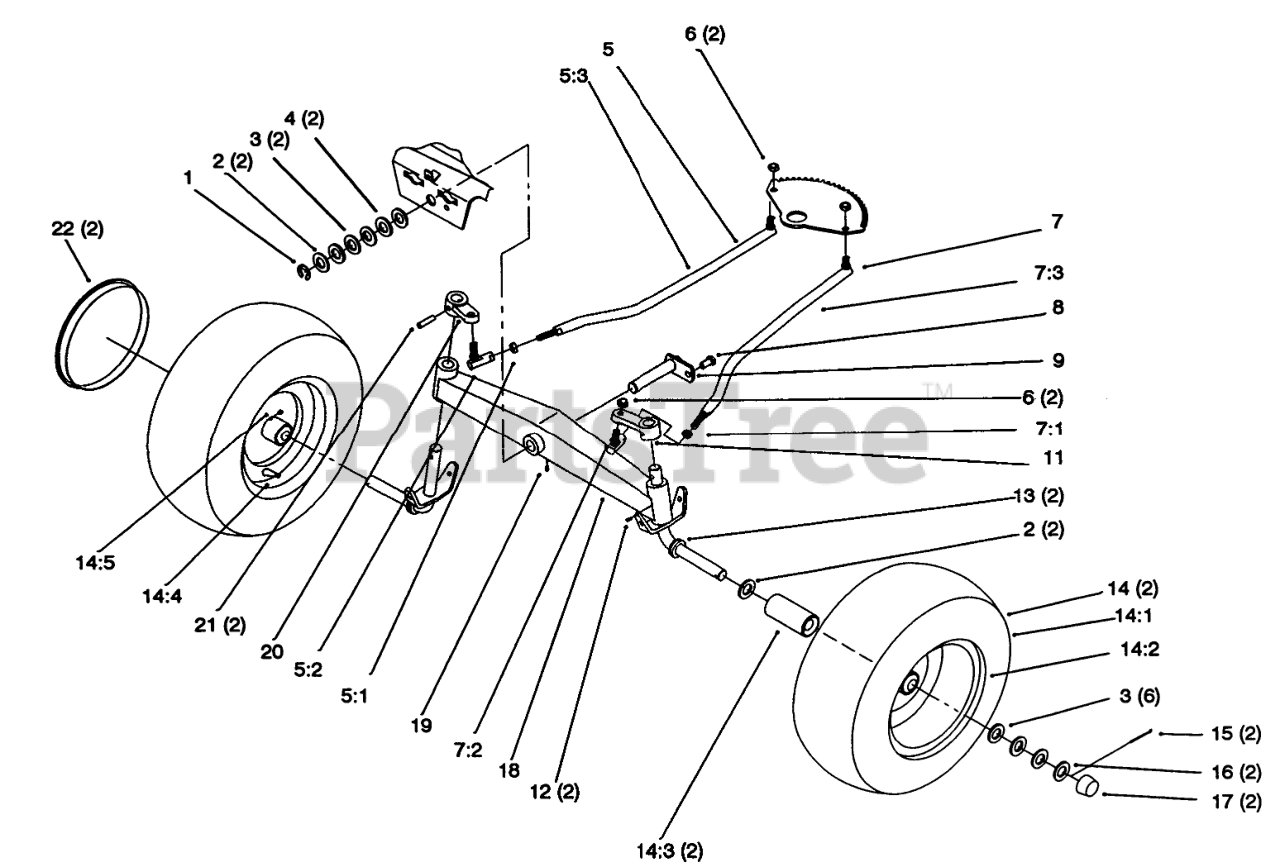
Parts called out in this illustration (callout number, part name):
1	E-RING
2	WASHER-SHIM
3	WASHER
4	Washer
5	LINKAGE-STEERING, RH
5:1	Nut-HJ
5:2	BALL-JOINT
5:3	Ball Link ASM
7	LINKAGE-STEERING, LH
7:1	Nut-HJ
7:2	BALL-JOINT
7:3	Ball Link ASM
8	SCREW-HWH, TAPTITE
9	PIN-AXLE
11	Arm-Front Spindle
12	FITTING-GREASE
13	SPINDLE
14	Wheel AND Tire ASM
14:1	Tire (16 x 6.5-8) 2-Ply -2 Wheel Axel
14:2	Wheel
14:3	BEARING-WHEEL
14:4	VALVE
15	PIN-COTTER
16	WASHER-PLAIN
17	CAP-HUB
18	AXLE-FRONT
19	FITTING-GREASE
20	Arm-Front Spindle
22	Hubcap (Only On: 72083)
